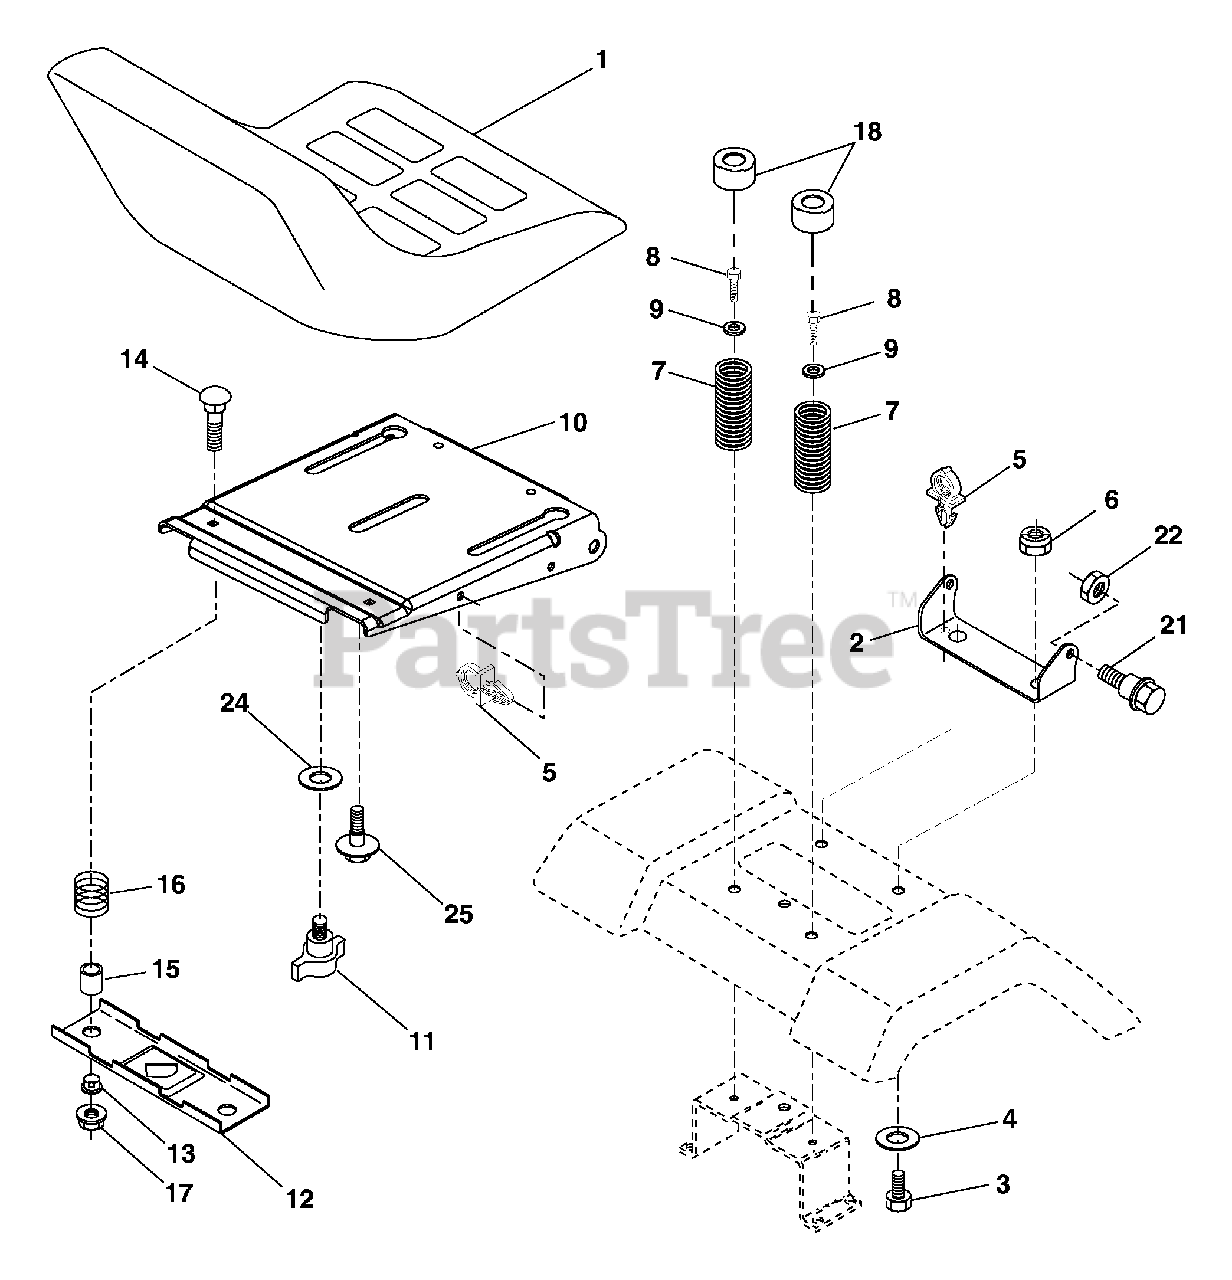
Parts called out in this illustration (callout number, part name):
1	Seat
2	Bracket Pivot Seat
3	Bolt Fin Hex 3/8-16 unc x 1
4	Washer Flat 13/32 x 1 x 10 Ga.
5	Clip Push-In
6	Nut Hex w/Ins. 3/8-16 unc
7	Spring Seat Cprsn 2 250 Blk Zi
8	Screw 3/8-16 x 1
9	Washer 13/32 x 1 x 14 Ga.
10	Pan Seat
11	Knob Seat Adj. Wingnut
12	Bracket Mounting Switch
13	Bushing Snap Blk Nyl 50 Id
14	Bolt Rdhd Sqnk 1/4-20 x 1-1/2
15	Spacer Split
16	Spring Cprsn
17	Nut Lock 1/4 Lge Flg Gr. 5 Zinc
18	Cap Spring Seat
21	Bolt Shoulder 5/16-18 unc
22	Nut Hex Lock W/Ins 5/16-18
24	Washer 17/32 x 1-3/16 x 12 Ga.
25	Bolt Shoulder 5/16-18 x 62
